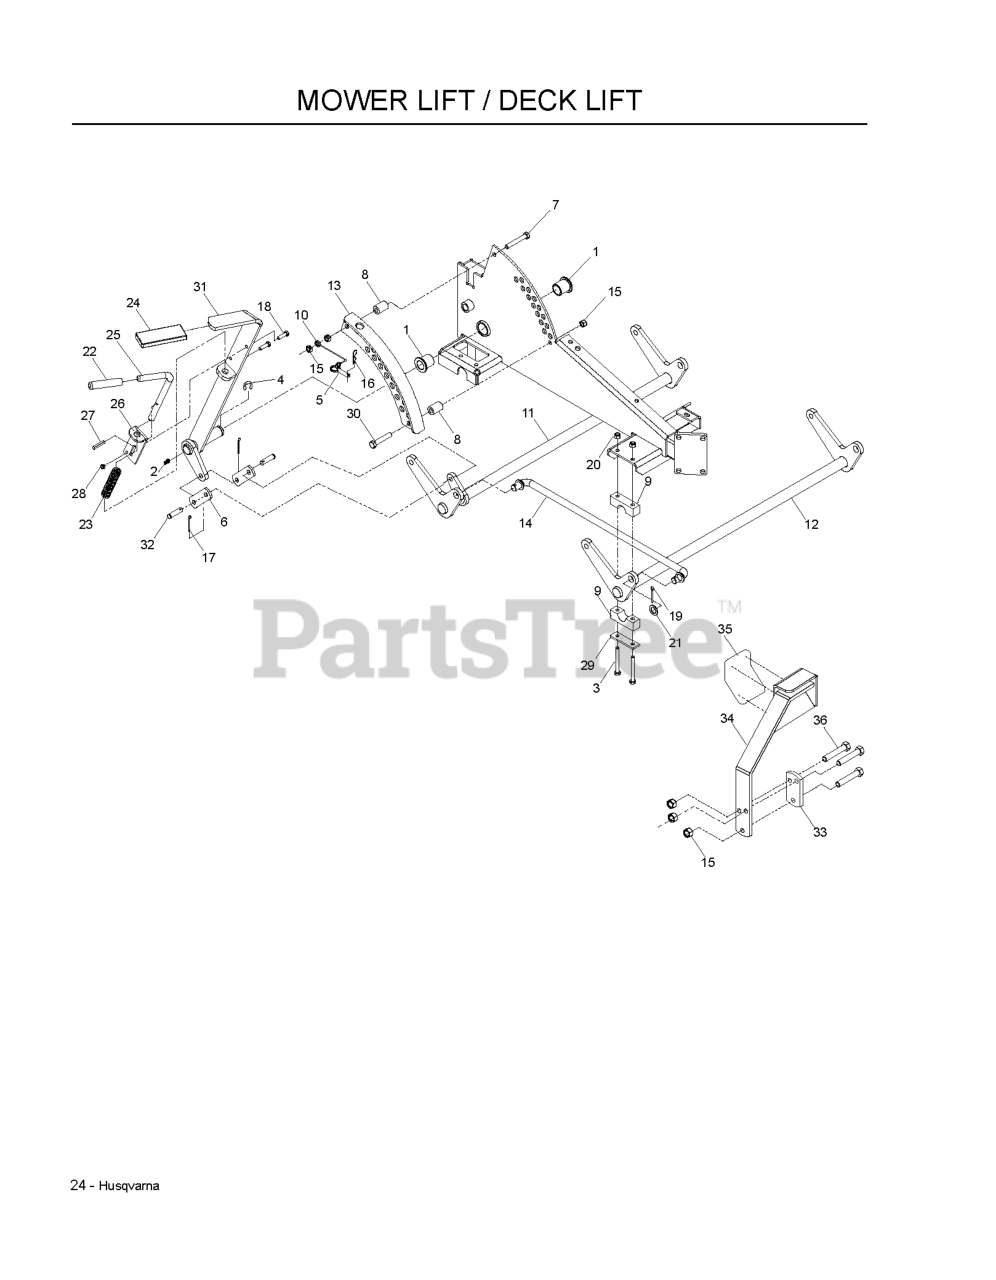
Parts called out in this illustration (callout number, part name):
1	BUSHING, FLANGED
3	HCS 5/16C X 2-3/4
4	E-RING 7/8
7	SCREW 3/8C X 2 3/4 HEX CAP
8	DECK LIFT SPACER
9	PILLOW BLOCK
11	REAR LIFT SHAFT
12	FRONT LIFT SHAFT
13	ADJUSTMENT PLATE WLDMT
14	CROSS LINK
15	NUT 3/8-16 NYLOC
16	HAIRPIN #4
17	RP_COTTER PIN 1/8 X 3/4
18	HCS 1/4C X 3/4 HCS
19	COTTER PIN
20	5/16-18 NYLOC FLANGE NUT
26	PIN MT, UPPER
28	NUT 1/4C CENTER LOCK
29	REINFORCEMENT BAR
30	HCS 3/8C X 2 1/2
31	LIFT LEVER WELDMENT
32	CLEVIS PIN 3/8 X 1 1/8
33	TIGHTENING PLATE BLK
34	LIFT PEDAL BLK
35	ANTI-SKID PAD
36	HCS 3/8C X 1 1/2
